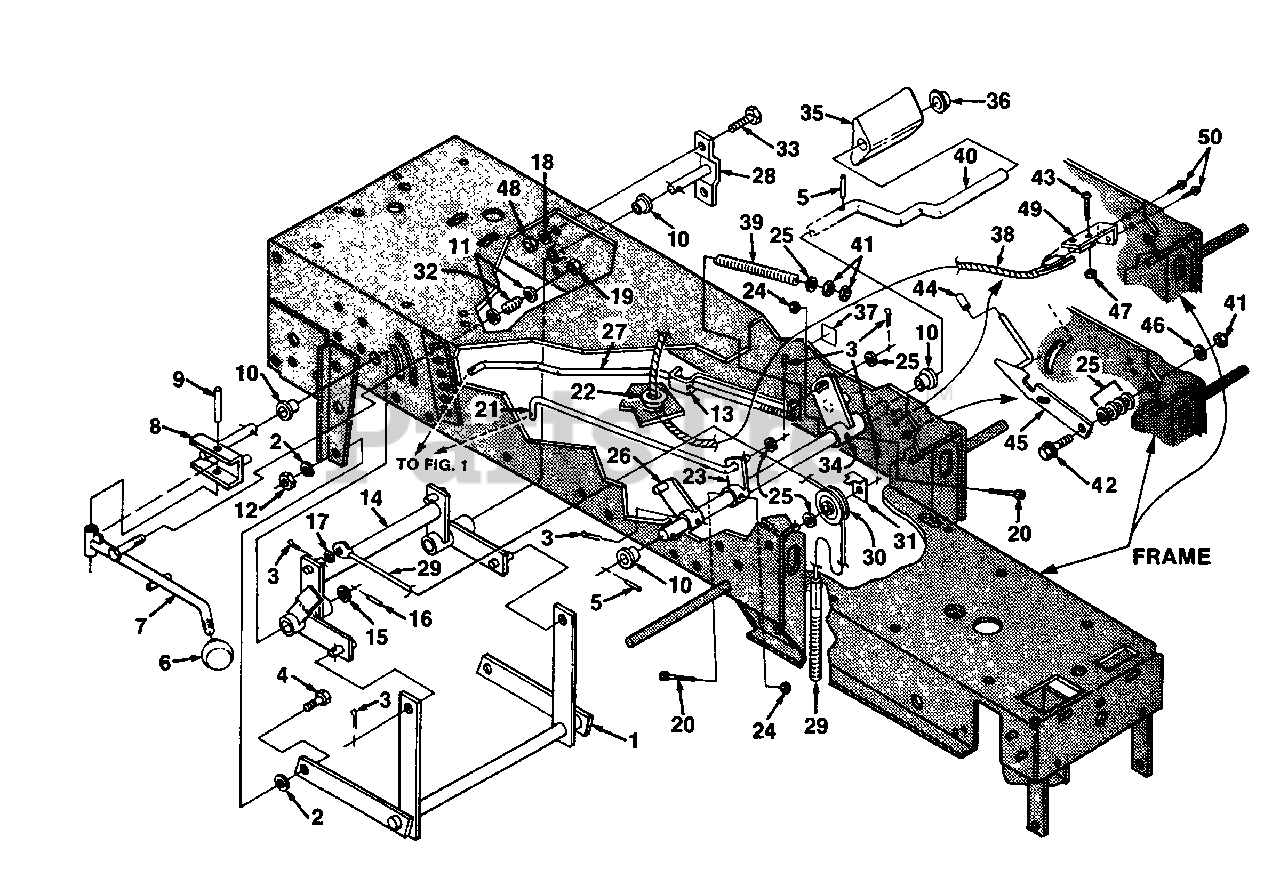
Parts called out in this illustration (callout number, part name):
1	LIFT BAR ASSY.
2	WASHER- Lock Hvy. (3/8")
3	PIN- Cotter (3/32 x 3/4")
4	BOLT- Shoulder
5	PIN- Roll (1/8 x 1")
6	KNOB Shift Lever
7	HANDLE ASSY.
8	HANDLE LIFT
9	PIN- Groove
11	WASHER- Flat (3/8")
12	NUT- Hex (3/8 x 16)
13	BRACKET- Brake Spring
14	REAR LIFT & BUSHING
16	PIN- Roll
17	WASHER- Flat (3/8")
18	WASHER- Lock (1/4")
19	NUT- Lock (5/16-18)
20	SCREW- Socket
21	ROD- Idler Act
22	BUSHING- Snap
23	LEVER- Clutch
24	NUT- C'Lock (#10-24)
25	WASHER- Flat (5/16")
26	ARM- Deactivating
27	ROD- Brake
28	FLANGE & ROD ASSY.
29	CABLE- Lift
30	PULLEY- Lift Cable
31	RETAINER- Cable
32	SPRING- Compression
34	BRAKE LEVER
35	PEDAL- Clutch
36	NUT- Push
37	DECAL- Park Brake
38	SWITCH- Safety
39	SPRING- Comp Brake
40	ARM- Brake/Clutch
41	NUT- (5/16-18)
42	BOLT- Shoulder (5/16-18)
43	SCREW- Slotted Truss Hd (#4-40 x 1)
45	LATCH & LEVER
46	WASHER- Lock Hvy (5/16")
47	NUT- Hex (#4-40)
48	NUT- Hex (1/4-20)
50	SCREW- (1/4-14 x .44")
